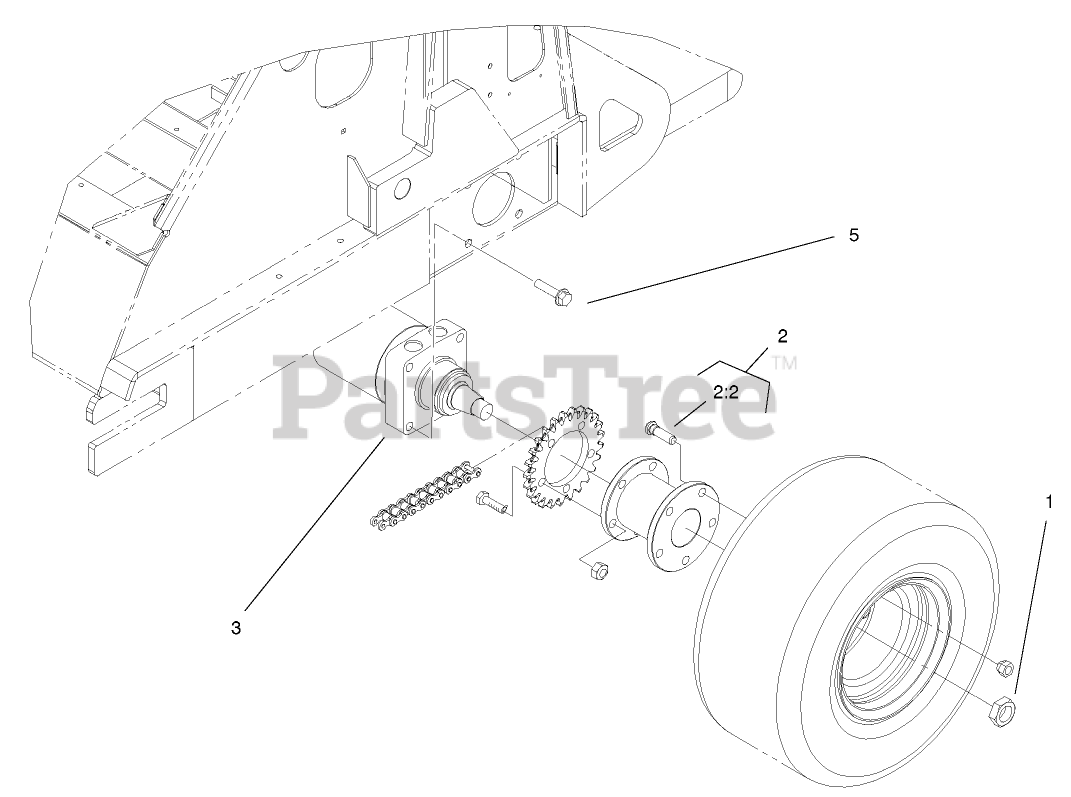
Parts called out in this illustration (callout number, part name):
1	NUT-LOCK
2	REAR HUB ASM
2:2	STUD-TYPE, DRIVE
3	HYD MOTOR ASM
5	SCREW-HHF
